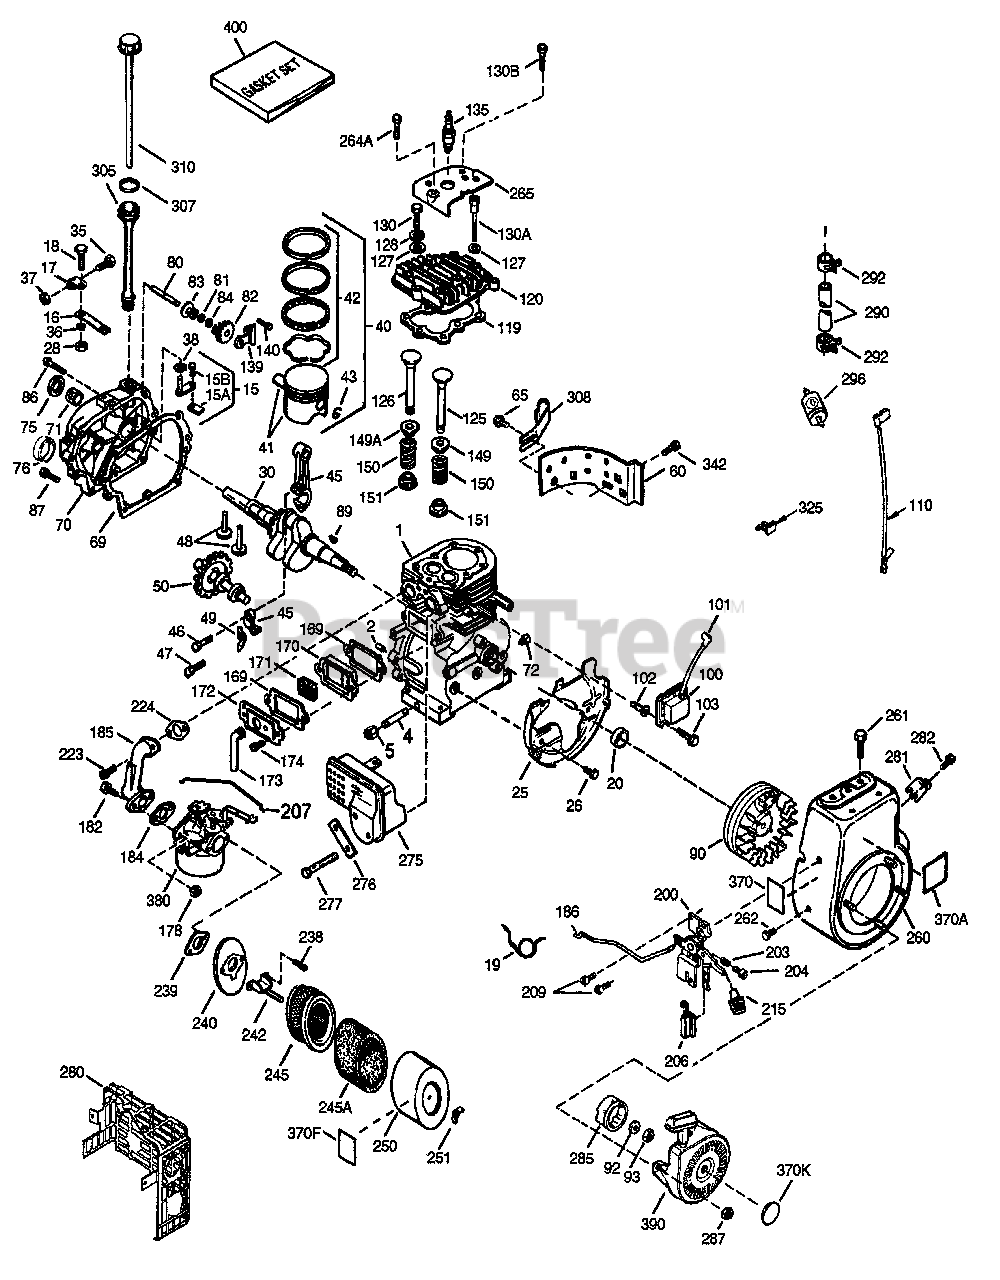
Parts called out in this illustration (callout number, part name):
2	Dowel Pin
4	Oil Drain Extension
5	Extension Cap
15	Governor Rod
15A	Governor Yoke
15B	Screw, 6-40 x 5/16"
16	Governor Lever
17	Governor Lever Clamp
18	Screw, 8-32 x 5/16"
19	Speed Control Spring
25	Blower Housing Baffle
26	Screw, 1/4-20 x 5/8"
28	Lock Nut, 8-32'
30	Crankshaft
35	Screw, 10-32 x 3/4"
36	Lock Washer
37	Lock Nut, 10-32'
38	Retaining Ring
40	Piston, Pin, Ring Set (Std)
41	Piston & Pin Assy (Std)
42	Ring Set (Std)
43	Piston Pin Retaining Ring
45	Connecting Rod Assy
46	Connecting Rod Bolt
47	Connecting Rod Bolt
48	Valve Lifter
49	Oil Dipper
50	Camshaft (MCR)
60	Blower Housing extension
65	Screw, 10-24 x 1/2"
69	Cylinder Cover Gasket
70	Cylinder Cover
71	Crankshaft Bushing
72	Oil Drain Plug
76	Camshaft Seal
80	Governor Shaft
82	Governor Gear Assy
83	Governor Spool
84	Retaining Ring
86	Screw, 1/4-20 x 1-3/16"
87	Screw, 1/4-20 x 1-11/16"
89	Flywheel Key
92	Lock Washer
93	Flywheel Nut
100	Solid State Ignition
101	Spark Plug Cover
102	Solid State Mounting Stud
103	Screw, Torx T-15, 10-24 x 15/16"
110	Ground Wire
119	Cylinder Head Gasket
120	Cylinder Head
125	Exhaust Valve (Std)
126	Intake Valve (Std)
128	Belleville Washer
130	Screw, 5/16-18 x 2"
130A	Screw, 5/16-18 x 1-3/4"
130B	Screw, 1/4-20 x 5/8"
135	Resistor Spark Plug
139	Governor Gear Bracket
140	Screw, 10-24 x 1/2"
149	Valve Spring Cap
149A	Valve Spring Cap
150	Valve Spring
151	Valve Spring Keeper
169	Valve Cover Gasket
170	Breather Body
171	Breather Element
172	Valve Cover
173	Breather Tube
174	Screw, 10-24 x 1/2"
178	Nut & Lock Washer, 1/4-28
182	Screw, 1/4-28 x 1"
184	Carburetor to Intake Pipe Gasket
185	Intake Pip
186	Governor Link
200	Control Bracket
203	Compression Spring
204	Screw, 5-40 x 7/16"
207	Throttle Link
209	Screw, 10-32 x 1/2"
215	Control Knob
223	Screw, Torx T-30, 5/16-18 x 1-1/8"
224	Intake Pipe Gasket
238	Screw, 10-32 x 1/2"
239	Air Cleaner Gasket
240	Air Cleaner Body
242	Air Cleaner Bracket
245	Air Cleaner Filter
245A	Air Cleaner Filter
250	Air Cleaner Cover
251	Wing Nut, 1/4-20
260	Blower Housing
261	Screw, 5/16-18 x 3/4"
262	Screw, Torx T-40, 5/16-24 x 21/32"
264A	Screw, 1/4-20 x 5/8"
265	Cylinder Head Cover
276	Locking Plate
277	Screw, 5/16-18 x 3-3/16"
280	Heat Shield
281	Starter Bubble Cover
282	Screw, 8-32 x 3/8"
285	Starter Cup
287	Nut & Lock Washer, 1/4-28"
290	Fuel Line
292	Fuel Line Clamp
296	Fuel Filter
305	Oil Fill Tube
308	Fill Tube Clip
325	Wire Clip
342	Screw, Torx T-30, 1/4-20 x 1/2"
370	Instruction Decal
370A	Throttle Decal
370F	Instruction Decal
370K	Starter Decal
380	Carburetor
390	Rewind Starter
400	Gasket Set
